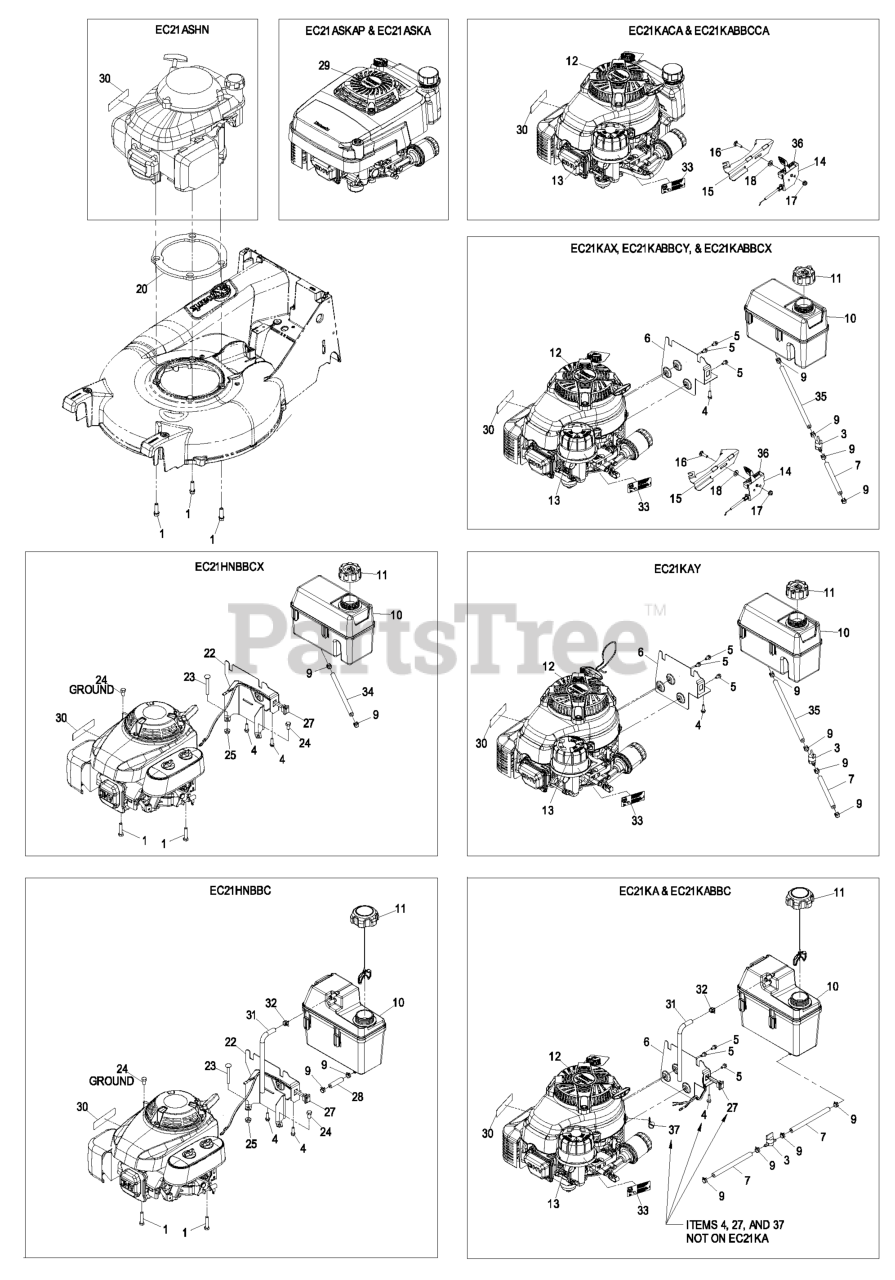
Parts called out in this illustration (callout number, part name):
1	SCREW-HH
3	VALVE-FUEL
4	SCREW-HWH
5	SCREW-HWH
6	BRACKET,FUEL TANK
7	HOSE-FUEL
9	CLAMP-HOSE
10	TANK-FUEL
12	DECAL
13	DECAL
14	THROTTLE-KAWASAKI W/O CHO
15	BRACKET-MOUNT, THROTTLE
16	SCREW-CARR
17	NUT-HF
18	WASHER-PLAIN
20	GASKET,DECK
23	SCREW-CARR
24	SCREW-HH
25	NUT-HF, NI
27	HARNESS,RUN/STOP
28	HOSE-FUEL
29	DECAL-RECOIL
30	DECAL-ARRESTER, SPARK
31	HOSE-VENT, CANISTER
33	DECAL, PRIMER
34	HOSE-FUEL
35	HOSE-FUEL
36	DECAL-THROTTLE / CHOKE
37	CLIP-LOOM
